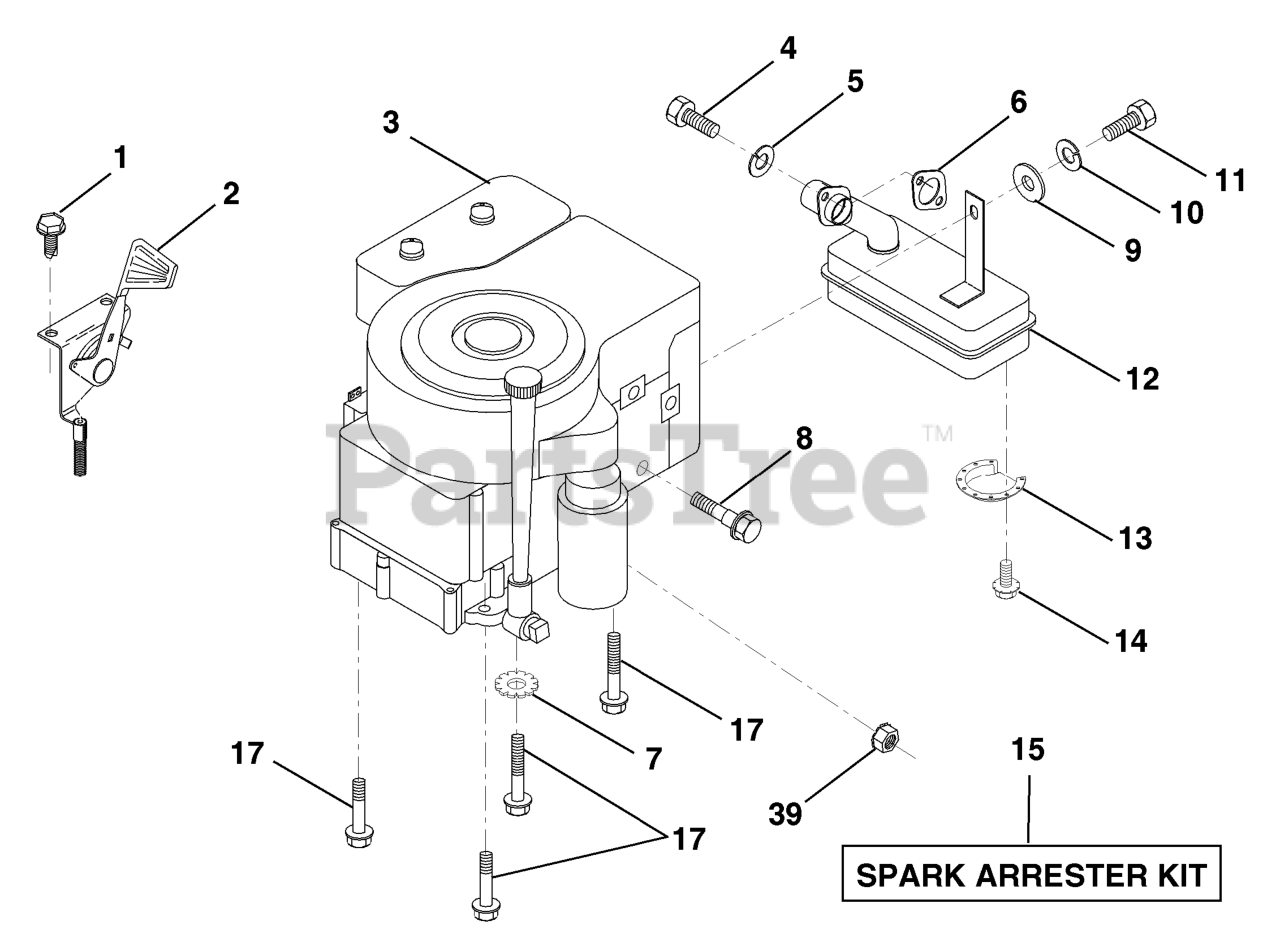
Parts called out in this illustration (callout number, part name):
2	CONTROL.TH/CH.RH.BLK.FLG.26
3	Engine
4	SCREW
5	WASHER.LOCK.HVY.HLCL.SPR.5/16
6	GASKET.ENG.1.313 ID.TIN PLATED
7	LOCKWASHER
9	WASHER
10	LOCKWASHER
11	Bolt, Hex Fin.
12	MUFFLER.SINGLE.B&S.12HP
13	DEFL MUFFLER LTV
14	SCREW
15	KIT.SPARK ARRESTOR 794945 B&S
17	SCREW LT
39	NUT FLANGE 1/4-20 STARTER NUT
